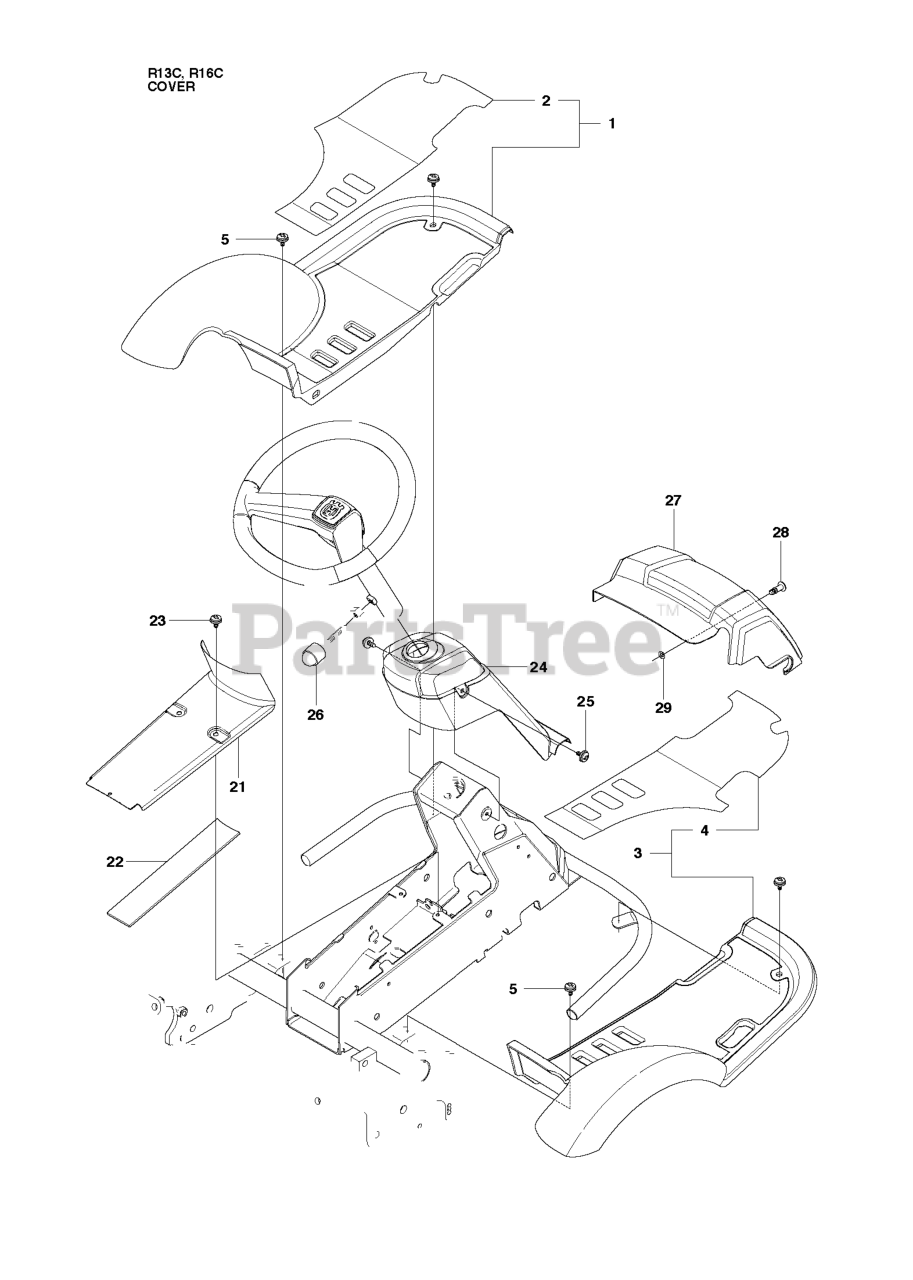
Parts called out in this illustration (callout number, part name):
1	FOOT PLATE
3	FOOT PLATE
26	PROTECTIVE COVER
